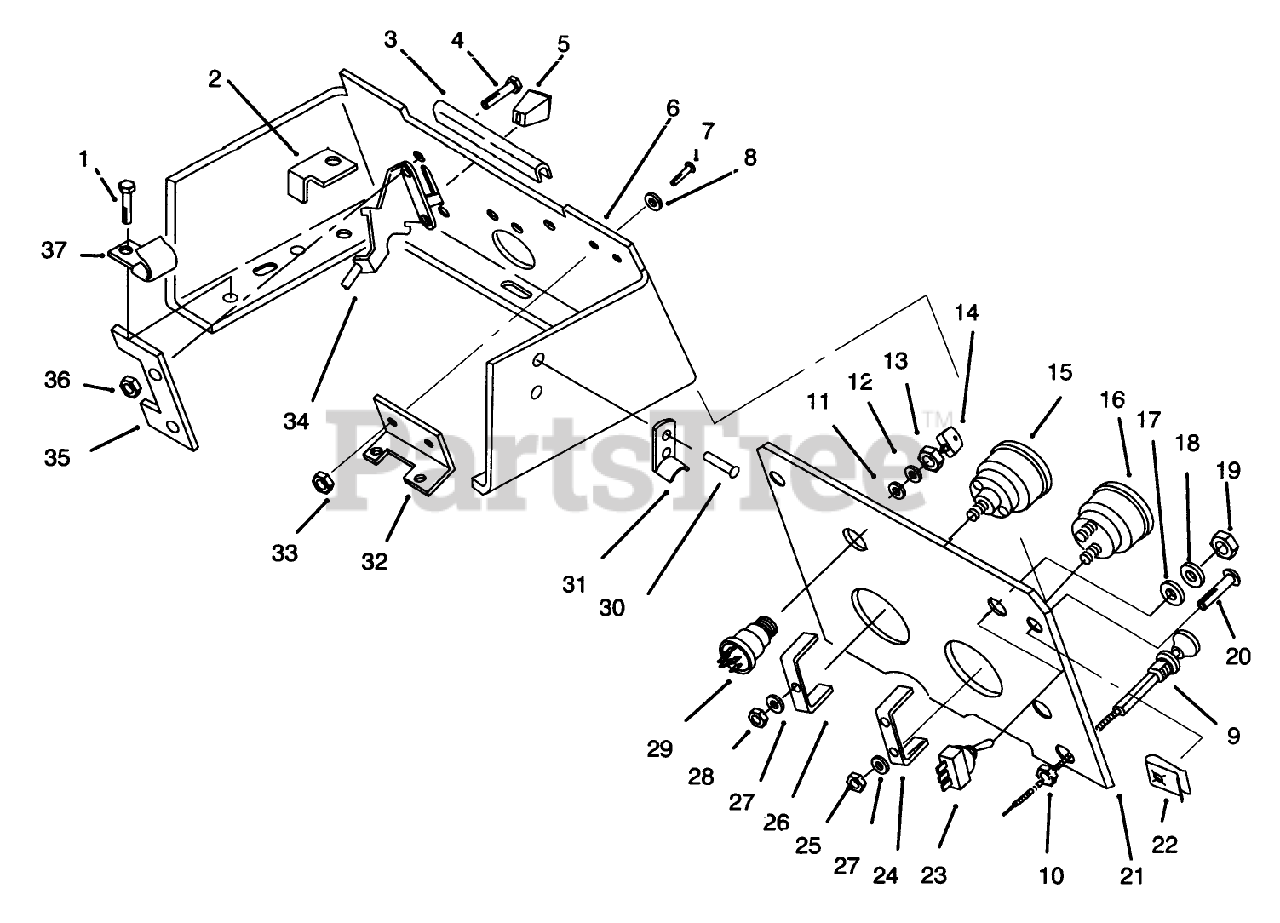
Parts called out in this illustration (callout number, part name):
2	STOP-PTO
3	EDGING-CONSOLE
4	SCREW-PPH
6	CONSOLE *B
7	SCREW-PAN
8	Washer-Lock
9	CONTROL-CHOKE
10	NUT-HEX PALNUT
14	KEY-IGNITION
16	VOLTMETER
17	WASHER
18	TAB-WASHER
19	*DISC**
20	SCREW-PPH
22	CLIP
23	SWITCH-LIGHTS
24	CLAMP-MOUNTING
25	HEX NUT 10-32 E.S. + + USE 3296-21 + +
26	CLAMP-HOUR METER
28	NUT-HEX
31	KEEPER-LATCH
32	BRACKET
34	CONTROL-THROTTLE
35	Washer
37	J-CLIP
